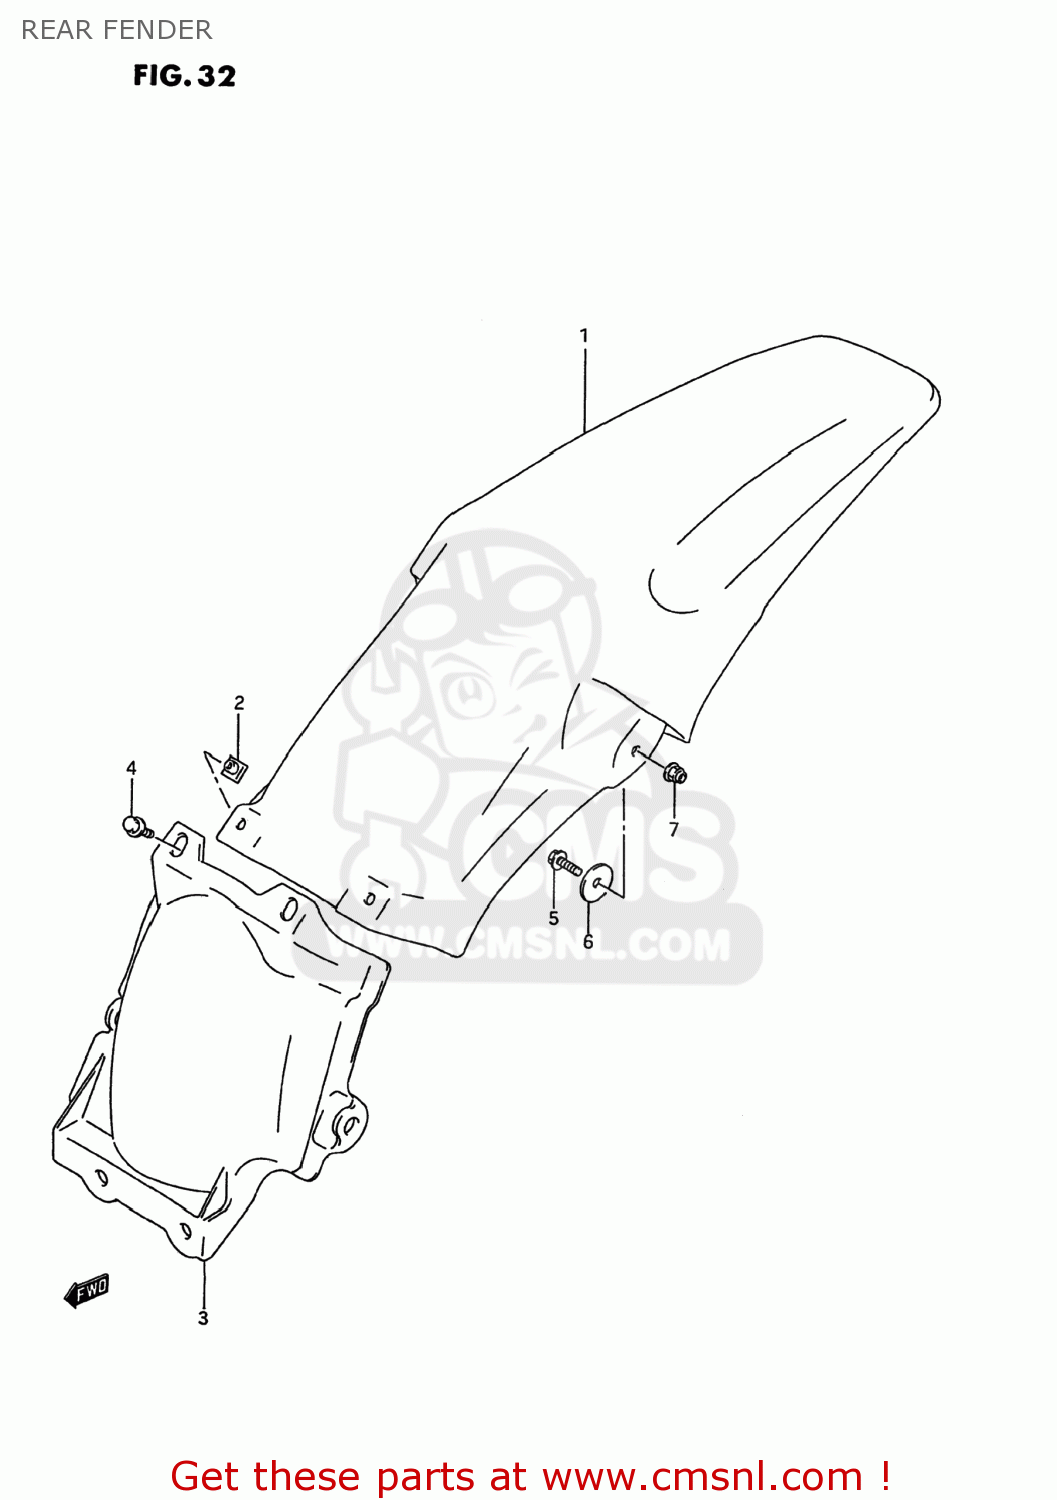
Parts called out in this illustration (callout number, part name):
1	BODY,RR FENDER RR
2	NUT,RR FENDER
3	BODY,RR FENDER FR
4	BOLT
5	BOLT
6	WASHER (6.5X29X1.6)
7	NUT
